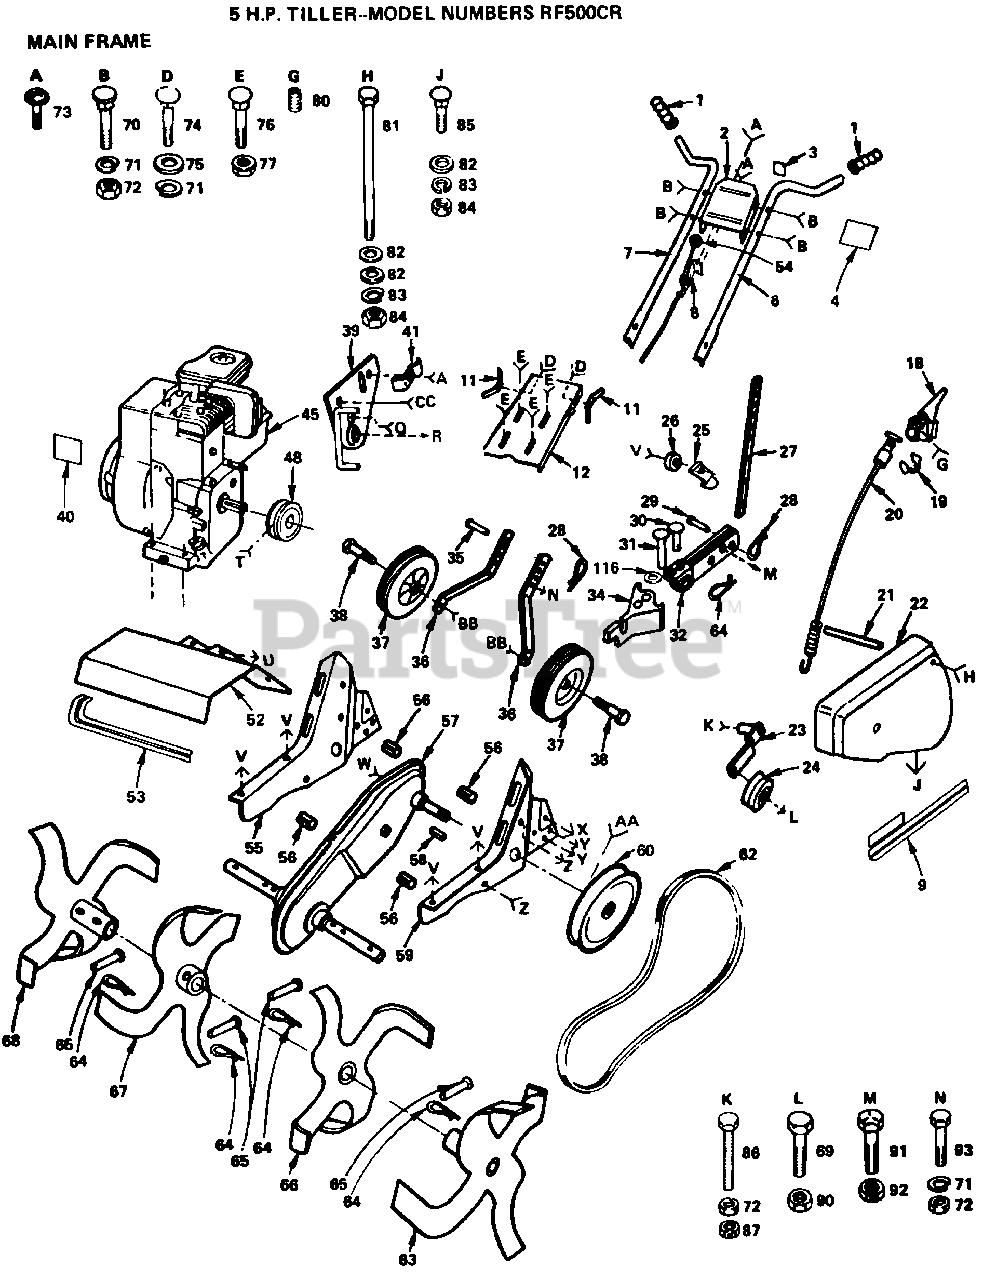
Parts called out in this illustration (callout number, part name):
2	BRACKET - HANDLE
3	DECAL - THROTTLE
8	THROTTLE CONT TI
9	DECAL - BELT GUARD
18	CONTROL LEVER TI
19	E-RING
20	CABLE CLUTCH T
21	SPLIT SPACER
23	IDLER ARM TI
25	STAKE SPRING TI
28	SPRING.RETAINER
31	RIVET
32	STAKE HOLDER TI
34	STAKE PIVOT TI
35	DRILLED RIVET RT
37	WHEEL TI
38	BOLT M
41	CONDIUT CLIP T
53	DECAL - TINE SHIELD
56	SPLIT SPACER RT
58	KEY T
59	ENGINE BRKT LH TI
60	TRANS SHEAVE RT
62	V BELT STD
63	TINE WELDMENT TI
64	RETAINER.SPRING
65	RIVET.PAN HD.1.75
66	TINE TI
67	TINE TI
68	TINE WELDMENT TI
71	LOCKWASHER
72	NUT.HEX.5/16-18
73	SCREW TI
74	BOLT
75	WASHER
77	NUT
80	SCREW
82	WASHER
83	LOCKWASHER
85	BOLT
90	NUT
92	GRIPCO NUT
